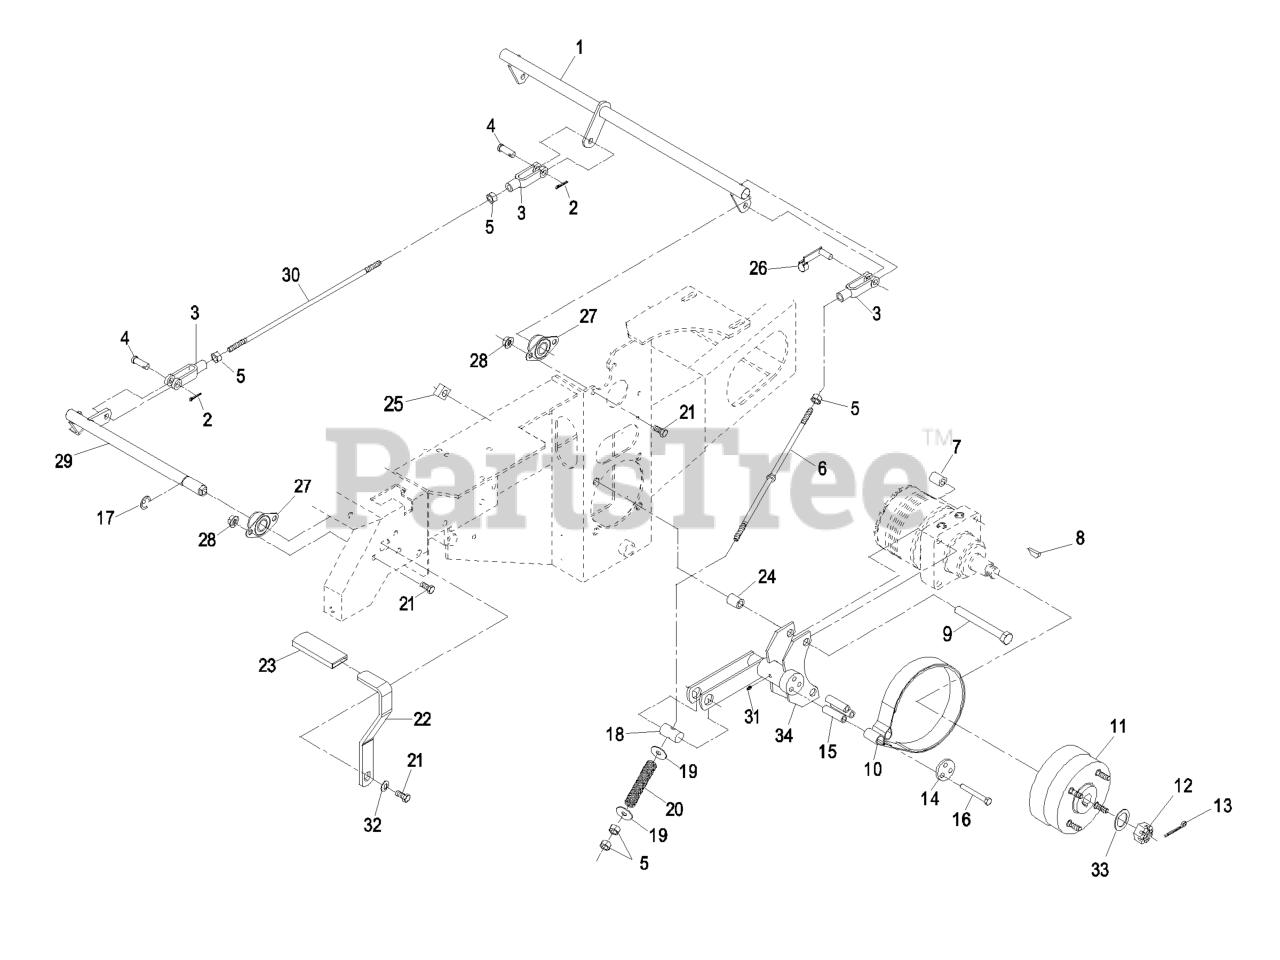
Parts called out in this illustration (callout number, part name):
1	CRANK-BRAKE, PARK
2	PIN-COTTER
3	YOKE-LINKAGE, BRAKE
4	PIN-CLEVIS
5	NUT-HEX
6	ROD-BRAKE
7	SPACER-WHEEL
8	KEY-WOODRUFF
9	SCREW-HH
10	BAND,BRAKE
11	WHEEL HUB ASM
13	PIN-COTTER
14	RETAINER-BAND, BRAKE
16	SCREW-HH
18	PIN-TRUNION
19	WASHER-FLAT
20	SPRING-BRAKE
21	SCREW-HH
22	ASM,BRAKE HANDLE W/ GRIP
23	GRIP-LEVER
24	SPACER-WHEEL
25	NUT-SQUARE, SPECIAL
26	PIN-SPRING, CLEVIS
27	BEARING-FLANGE, SIDE
28	NUT-HHF, WHIZ
29	SHAFT-BRAKE, PARKING
30	LINKAGE-HANDLE, BRAKE
31	FITTING-GREASE
32	WASHER-BELLEVILLE
33	WASHER-SPACER
34	BRACKET-BRAKE
